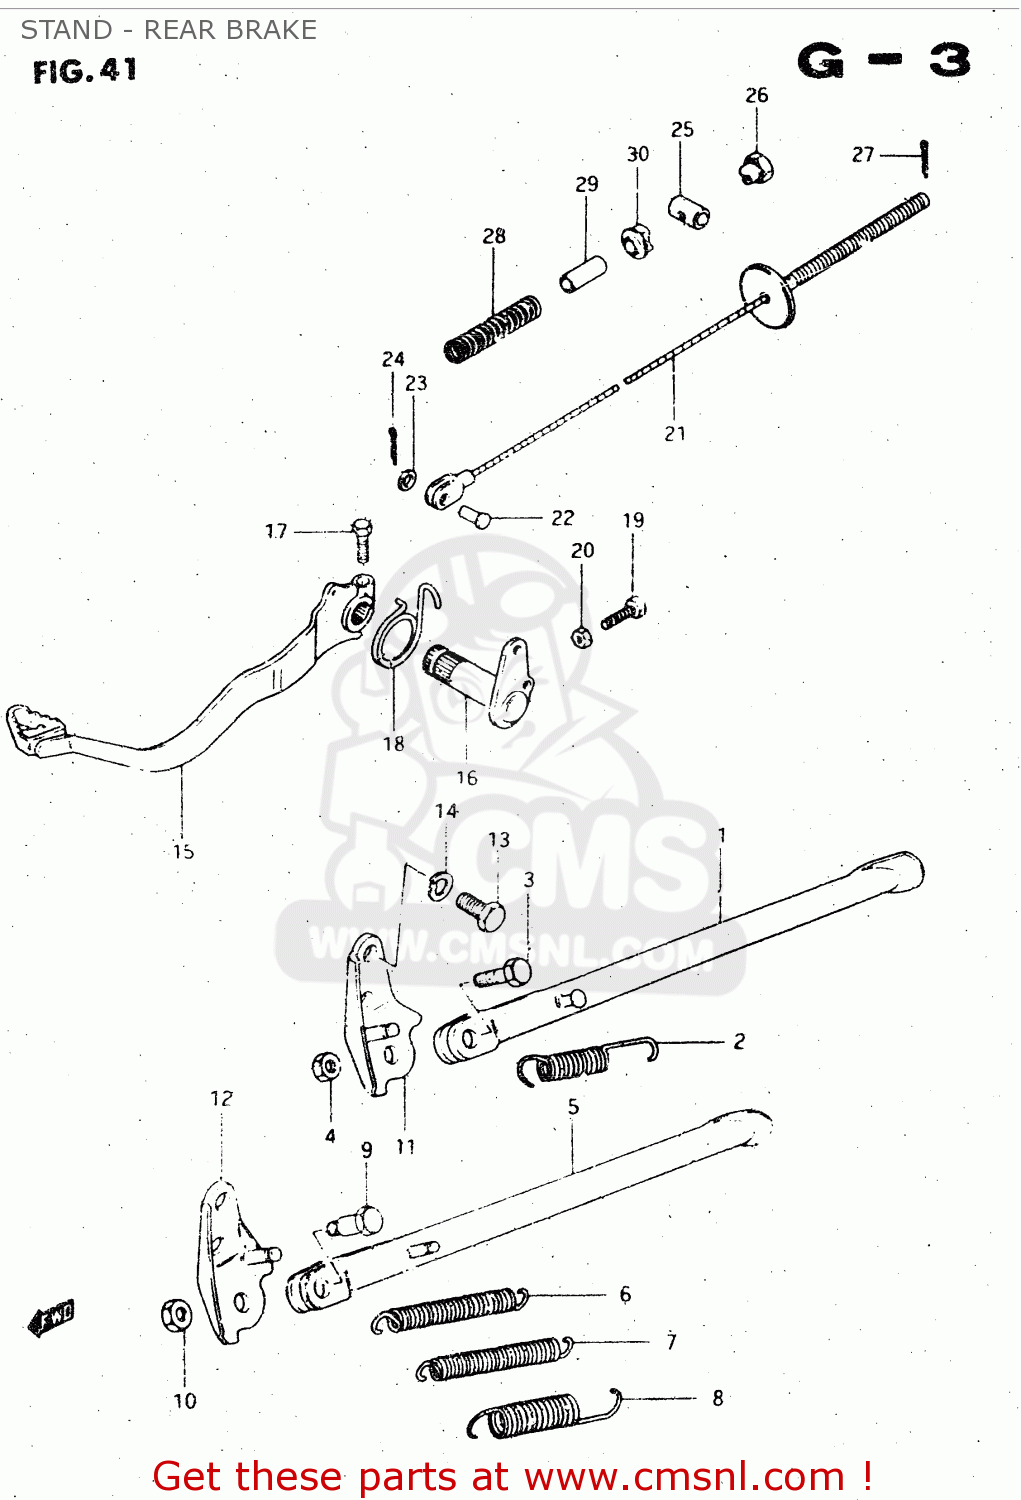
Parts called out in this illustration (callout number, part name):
1	STAND,SIDE
2	SPRING
3	BOLT(10X30)
4	NUT
5	STAND, PROP
6	SPRING
7	SPRING
8	SPRING, OUTER
9	BOLT L:30
10	NUT
11	BRACKET,PROP STAND
12	BRACKET, PROP STAND
13	BOLT(10X19)
14	LOCK WASHER
15	PEDAL,BRAKE
16	ARM,BRAKE PEDAL
17	BOLT
18	SPRING
19	BOLT(6X23)
20	NUT
21	CABLE,RR BRAKE
22	PIN(L:17.5)
23	WASHER
24	PIN
25	PIN,BRAKE CABLE ADJUSTER
26	NUT (6MM)
27	PIN
28	SPRING
29	CUSHION,FR GRILLE,UPPER
30	CUSHION
